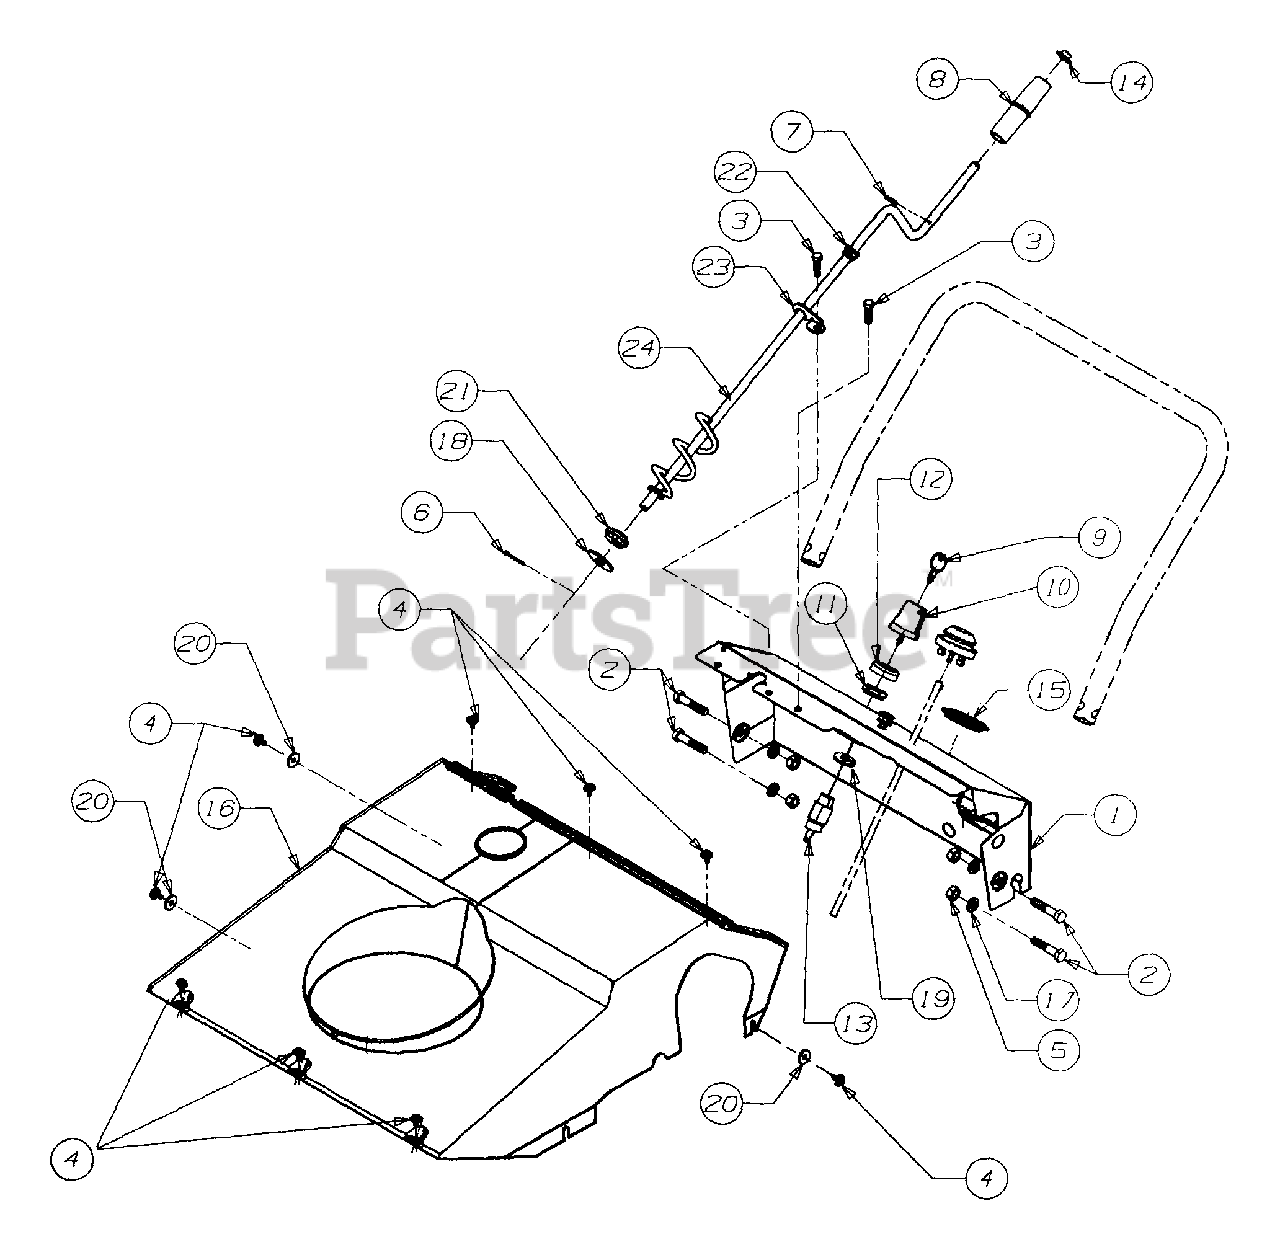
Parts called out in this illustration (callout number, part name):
3	Scr., Hex Hi-Low Scr. 1/4 x .75
4	Scr., Hex B-Tapp Wash. #10-16 x .38
5	Nut, Hex 5/16-18 Gr. 2
6	Pin, Cotter 3/32 x .75
7	Roll Pin 1/8 O.D. x .63 Lg.
8	Knob, Chute Crank
9	Key, Ignition
10	Key, Ignition W/O Logo
11	Ignition Switch Nut 5/8-32
12	Ignition Switch Cap
13	Switch, Key Recoil Start
14	Cap, Push
15	Snap - In Plug (142 Only)
16	Shroud
17	L-Wash. 5/16 I.D.
18	Wash., Flat 3/8 x 3.25 x .100
19	Intern. L-Wash. 5/8 x 1.058 x .046
20	Fl-Wash. .194 x .62 O.D. x .063
21	Hex Bushing
22	Bushing, Plastic
23	Upper Chute Crank Brkt.
24	Chute Crank
